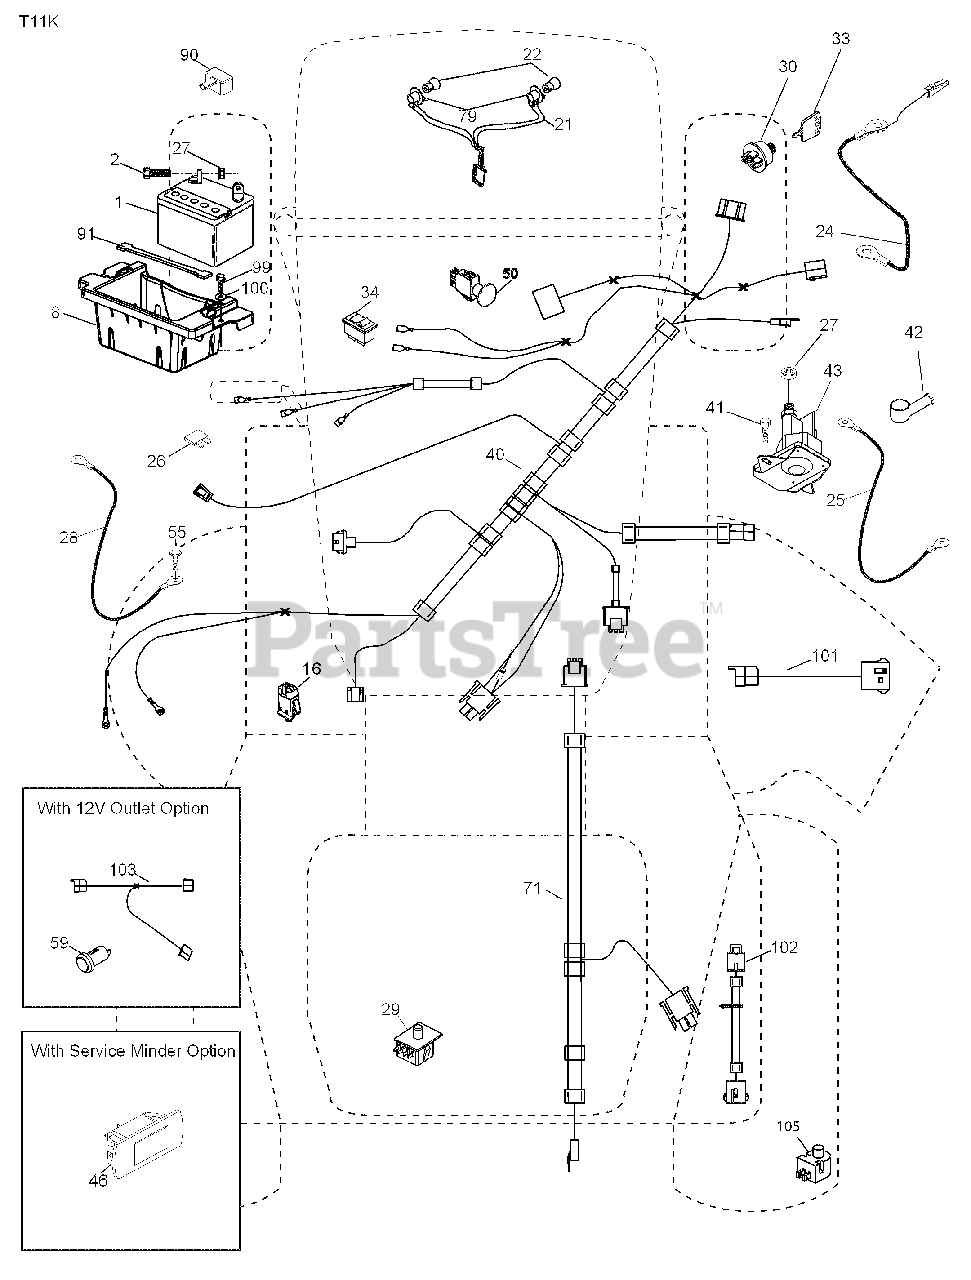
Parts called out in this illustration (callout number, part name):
1	Battery
2	Bolt Hex Hd 1/4-20 unc x 3/4
8	Battery Box
16	Switch Interlock
21	Harness Socket Light
22	Bulb, Light #1156
24	Cable Battery
25	Cable Starter
27	Nut Keps Hex 1/4-20 unc
28	Cable Ground 21" Blk 6 Ga.
29	Switch Seat
30	Switch Ign
34	Switch Light/Reset
40	Harness Ign. Dash
41	Screw Thd Cut 1/4-20 x 1/2
42	Cover Terminal Red
43	Solenoid
46	Gauge Hourmeter
50	Switch PTO
55	Screw Thdrol 5/16-18 x 3/4
71	Harness Ign
79	Socket Asm. Bulb Twistlock
90	Cover Terminal Battery
91	Strap Battery
99	Screw Hexwsh Thdrol 1/4-20 x 3/4
100	Washer 9/32 x 7/8 x 16 Ga.
101	Pigtail Harness Clutch
102	Harness Pigtail
105	Switch Reverse TT Pedal
